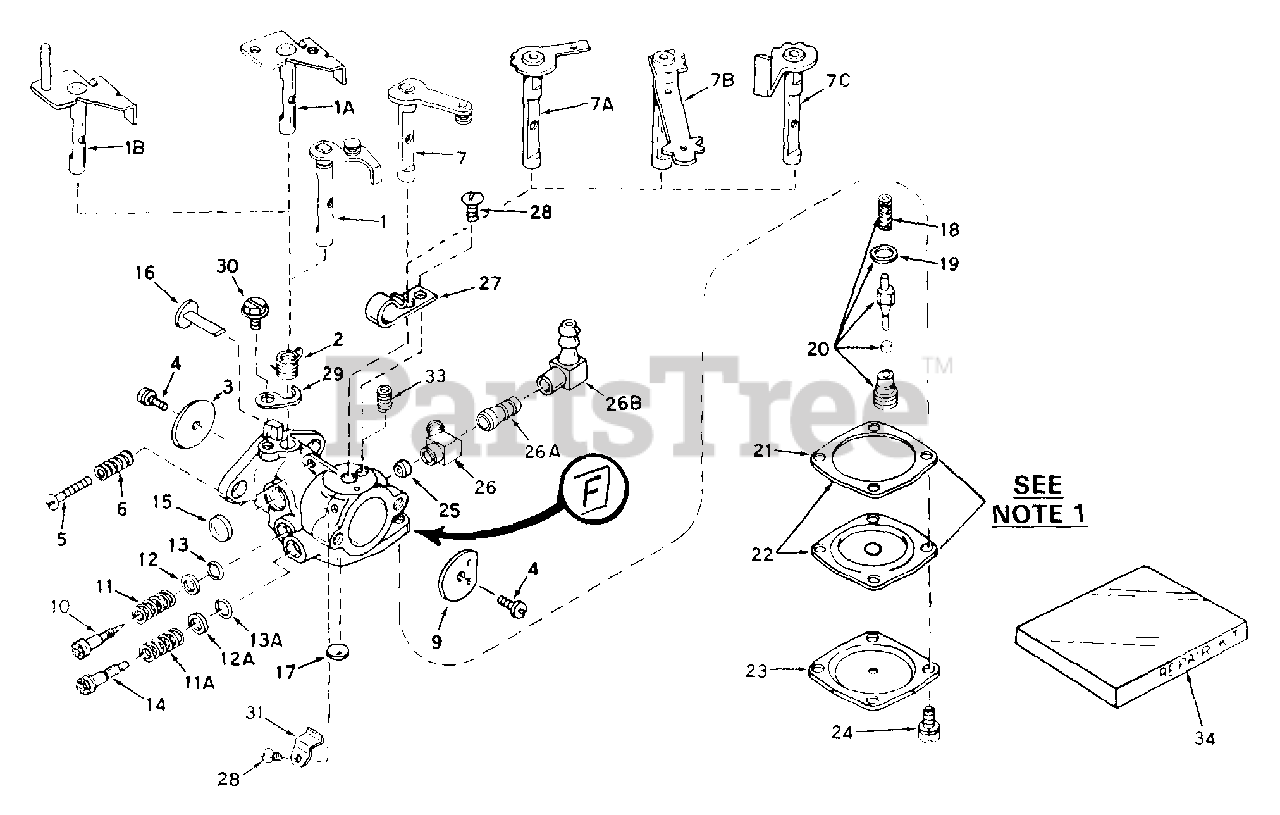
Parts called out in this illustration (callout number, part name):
1A	"Shaft & Lever Assy., Throttle
2	Spring, Throttle return
3	Shutter, Throttle
4	Screw, Throttle & Choke shutter
5	Screw, Idle regulating
6	Spring, Idle speed screw
7A	Shaft & Lever Assy., Choke
9	Shutter, Choke
10	Screw, Idle adj.
11	Spring, Idle adj. screw
11A	Spring, Main adj. screw
12	Washer, Idle adj. screw
12A	Washer, Main adj. screw
13	"O" Ring, Idle adj. screw
13A	"O" Ring, Main adj. screw
14	Screw, Main adj. (.0225 da. hole)
15	Plug, Welch
16	Element, Pump
17	Plug, Welch
18	Spring, Valve
19	Gasket, Valve seat
20	Inlet Needle, Seat, Gasket & Spring A ssy.,
21	Gasket, Diaphragm
22	Diaphragm Assy.
23	Cover, Diaphragm
24	Screw, Cover
25	Valve, Check
26	Fitting, Fuel inlet
27	Spring, Detent
28	Screw, Detent spring
29	"Retainer, Throttle shaft
30	Screw, Retainer
34	Repair Kit
